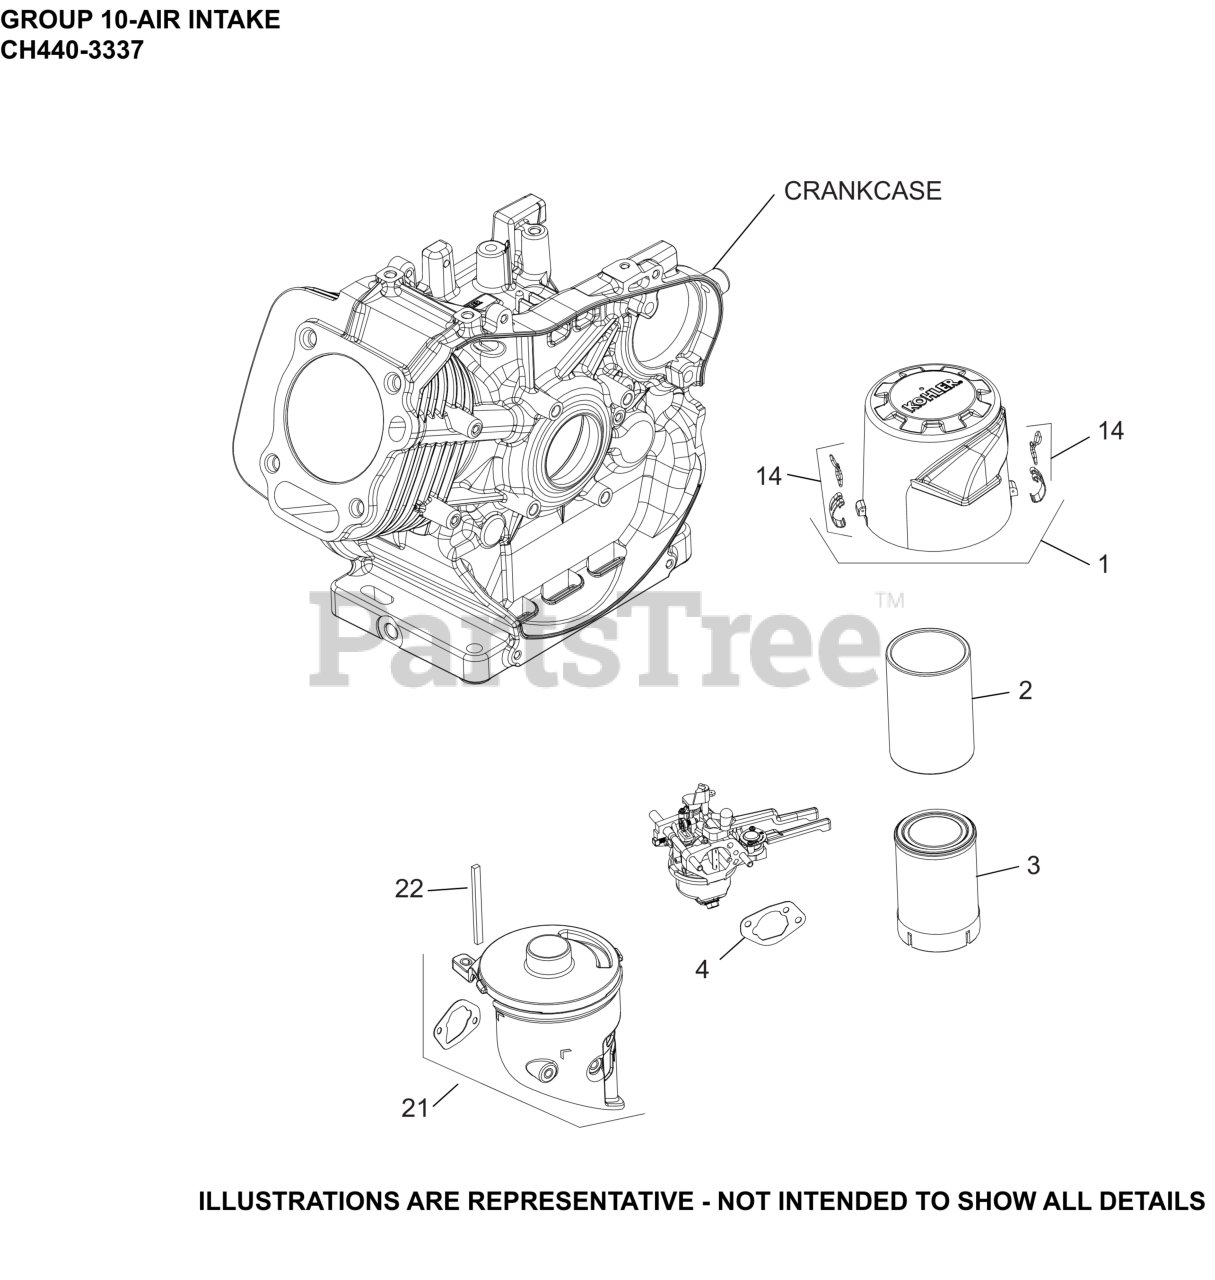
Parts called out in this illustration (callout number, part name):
1	COVER, AIR CLEANR ASSEMBLY
2	ELEMENT, PRE-CLEANER
3	ELEMENT, AIR FILTER
4	GASKET, AIR CLEANER
14	KIT, LATCH CLIP
21	KIT, AIR CLEANER BASE ASSEMBLY
